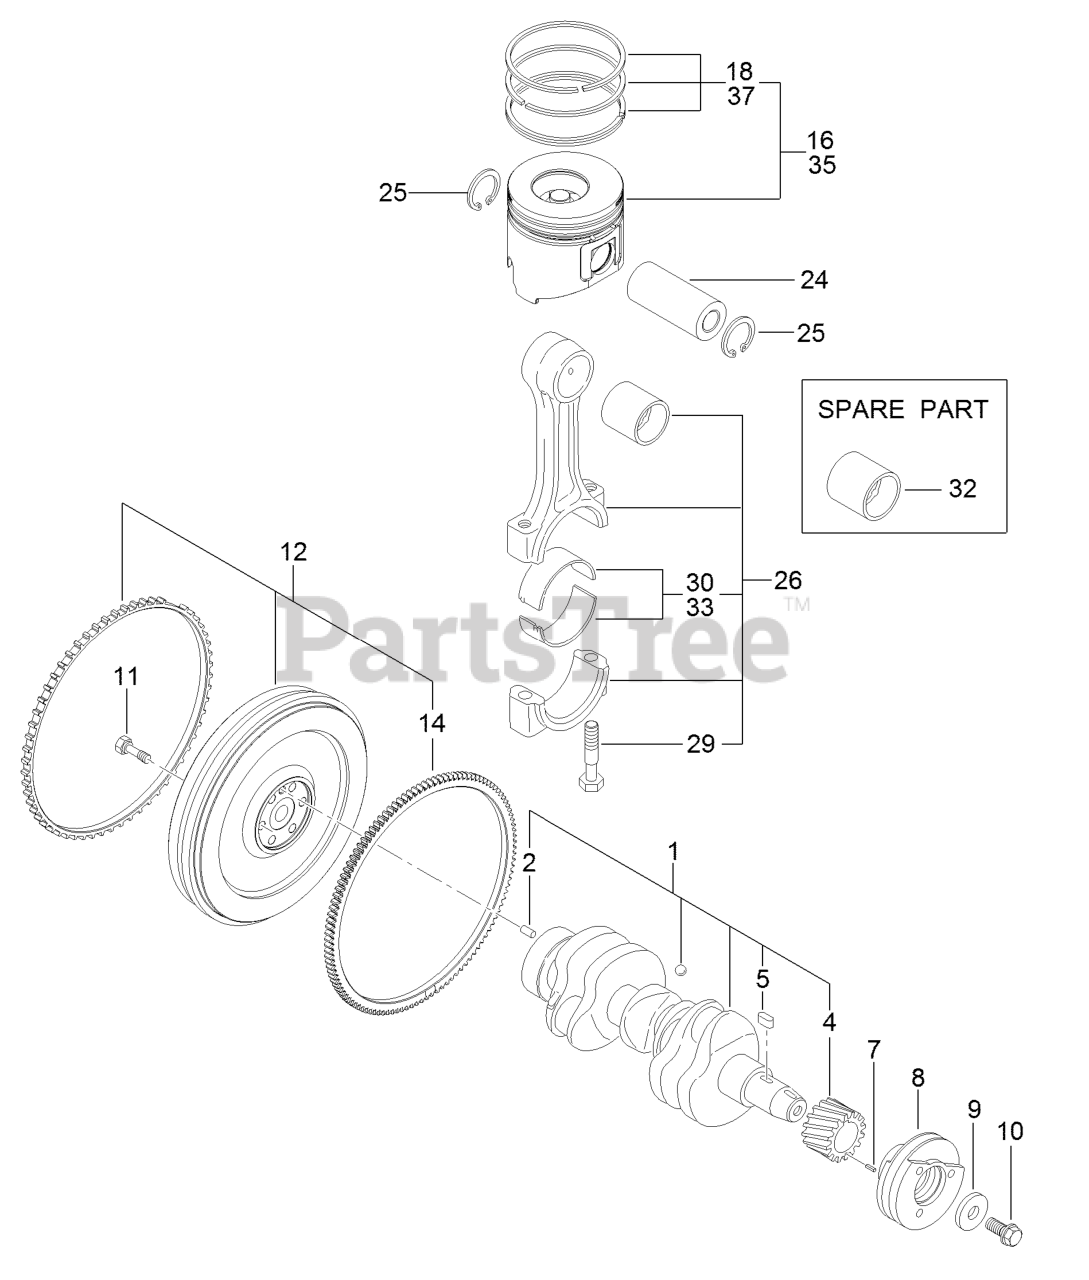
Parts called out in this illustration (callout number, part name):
1	Crankshaft ASM
7	Pin-Spring
8	Pulley-V
12	Flywheel ASM
16	Piston ASM
18	Piston Ring ASM
26	Connecting Rod ASM
30	Pin-Crank
32	Pin-Piston
33	Pin-Crank (.25)
35	Piston ASM (0.25 O S)
37	Ring Set (0.25 O S)
